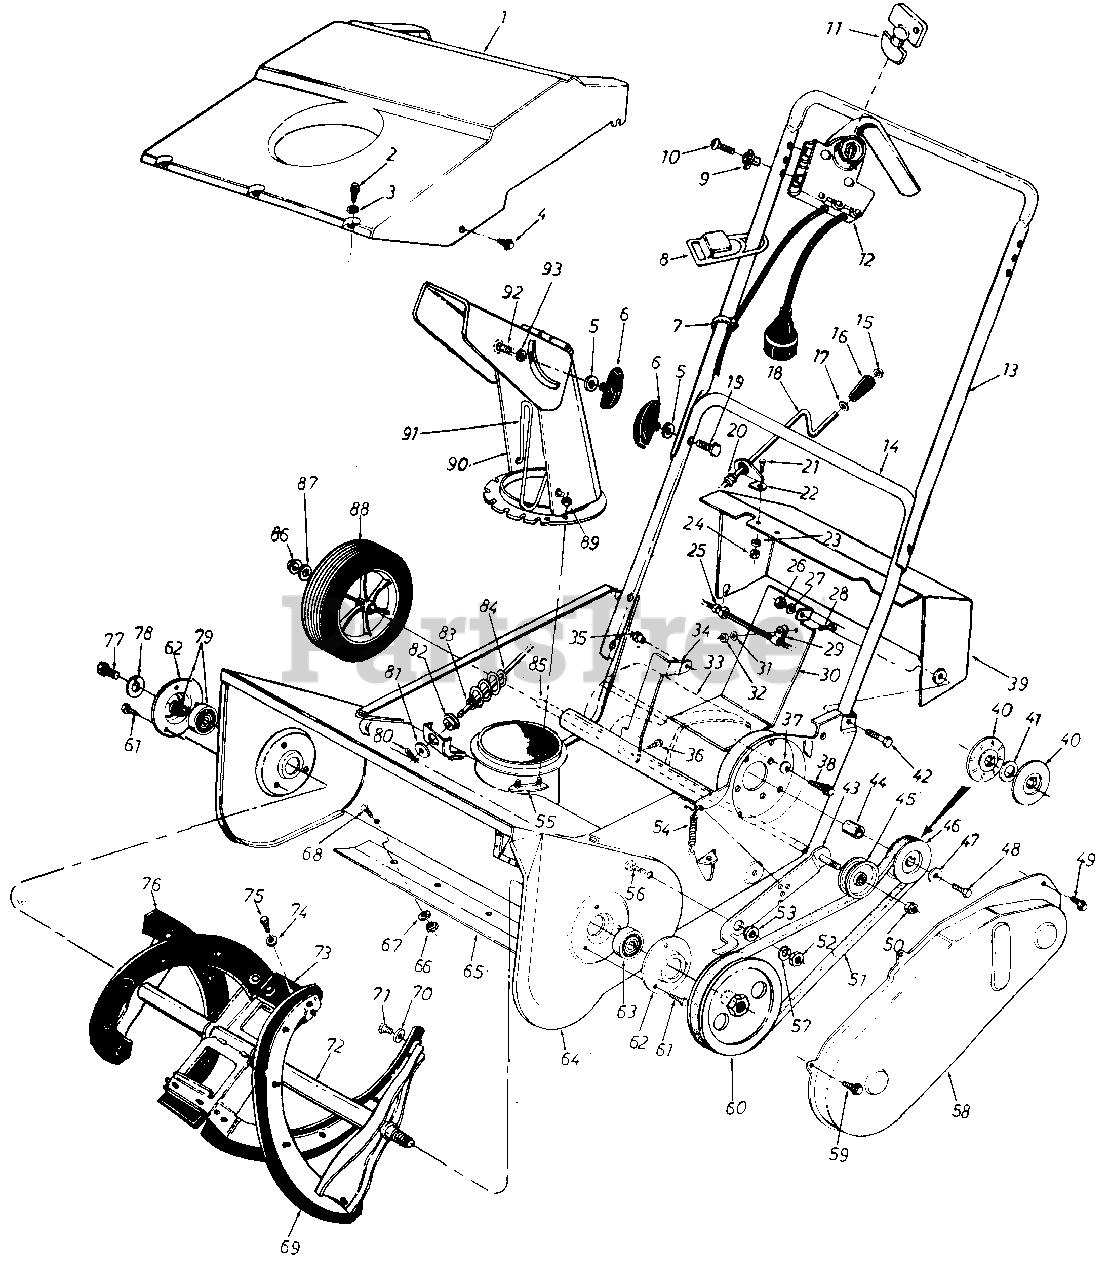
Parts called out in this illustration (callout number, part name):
1	21" Snow Thrower Shroud
2	Hex B Tap Scr. #10 x .38" Lg.
3	Spr.-Wash. .206" I.D. x .448" O.D.
4	Hex L-Wash. Hd. AB-Tap Scr. 1/4 x.62" Lg.
5	Bell-Wash. .345" I.D. x .88" O.D.
6	Hand Knob
7	Cable Tie
8	Cord Restraint
9	Insulating Spacer
10	Fl-Countersunk Scr. #10-24 x 1 5" Lg.
12	Electric Control w/Key
13	Upper Handle
14	Lower Handle
15	Push Nut for 3/8" Rod
16	Knob
17	Fl-Wash. .385 I.D. x .62" O.D.
18	Chute Crank Ass'y.-L.H.
19	Curved Hd. Bolt 5/16-18 x 1.75 " Lg.
20	Chute Crank Grommet
21	Hex Bolt '/4-20 x .50" Lg.
22	Upper Chute Crank Brkt.
23	L-Wash. 1/4" I.D.
24	Hex Nut 1/4-20 Thd.
25	Cord Restraint
26	Hex Nut 5/16-18 Thd.
27	L-Wash. 5/16" I.D.
28	Truss Mach. Scr. #10-24 x .50" Lg.
29	Cord Restraint
30	21" Blower Housing Ass'y.
31	Ext. L-Wash. #10
32	Hex Nut #10-24 Thd.
33	Electric Motor 120V
34	Motor Support Brkt.
35	Motor Shroud w/Hdwe.
36	Hex L-Wash. Hd. AB-Tap 1/4" x .62" Lg.
37	L-Wash. 5/16" I.D.
38	Hex Bolt 5/16-18 x .50" Lg.*
39	Dash Panel
40	3/8-V-Pulley Half .625" I.D. x 2.25
41	Bell-Wash. .345" I.D. x .88" O.D.
42	Hex Bolt 5/16-18 x 1.50" Lg.
43	Idler Brake Brkt. Ass'y.
44	Spacer .635" I.D. x .890" O.D. x .80" Lg.
45	Fl-Idler w/Flanges 2.12" O.D.
46	3/8-V-Pulley Half .625" I.D. x 2.25
47	Bell-Wash. .345" I.D. x .88" O.D.
48	Hex Bolt 5/16-24 x .75" Lg.
49	Hex L-Wash. Hd. AB-Tap 1/4" x .62" Lg.
50	Hex Patch L-Nut 3/8-24 Thd.
51	V-Belt 1/2" x 34.0" Lg.
52	Hex Nut 5/16-18 Thd.
53	Shld. Spacer. 500" Dia. x .27" Lg.
54	Extension Spring
55	Chute Flange Keeper Ass'y.
56	Truss Mach. Scr. 5/16-18 x .75" Lg.
57	L-Wash. 5/16" I.D.
59	Hex B-Tap Scr. 1/4 x .38" Lg.
60	Flat Pulley 5.06" O.D. 1/2-20-L.H.
61	Hex B-Tap Scr. 1/4 x .38" Lg.
64	21" Blower Housing Ass'y.
65	Shave Plate
66	Hex Nut 1/4-20 Thd.
67	Bell-Wash. .265" I.D. x .75" O.D.
68	Carriage Bolt 1/4-20 x .62" Lg.*
69	Rubber Spiral 8.62" Dia.-L.H.
70	Fl-Wash. .281" I.D. x .50" O.D.
71	Hex Wash. B-Tap Scr. 1/4 x .62" Lg. Spec.
72	Auger Ass'y. 21"-8.62" Dia.
73	Rubber Paddle
74	Fl-Wash. .218" I.D. x .62" O.D.
75	Hex Wash. B-Tap Scr. #10 x .62" Lg.
76	Rubber Spiral 8.62" Dia.-R.H.
77	Hex Wash. TT-Tap Cl-Scr. 1/4-20 x .75" Lg.
78	L-Wash. 1/4" I.D.
79	Kit-Bearing and Collar
80	Cot-Pin 3/32 Dia. x .75" Lg.
81	Fl-Wash. .385" I.D. x 1.50" O.D.
82	Hex Bushing .385" I.D.
83	Fl-Wash. .385" I.D. x .62" O.D.
84	Chute Crank Ass'y.-L.H.
85	Wheel Axle Tubing
86	Push Cap 1/2" Dia.
87	Fl-Wash. .510" I.D. x .75" O.D.
88	Plastic Wheel Ass'y. 6 x 1.50"
89	Hex L-Nut 1/4-20 Thd.
90	5.0" Dia. Chute Ass'y.
91	Chute Ass'y. Guard
92	Carriage Bolt 5/16-18 x .62" Lg.
93	Fl-Wash. .328" I.D. x .68" O.D.
